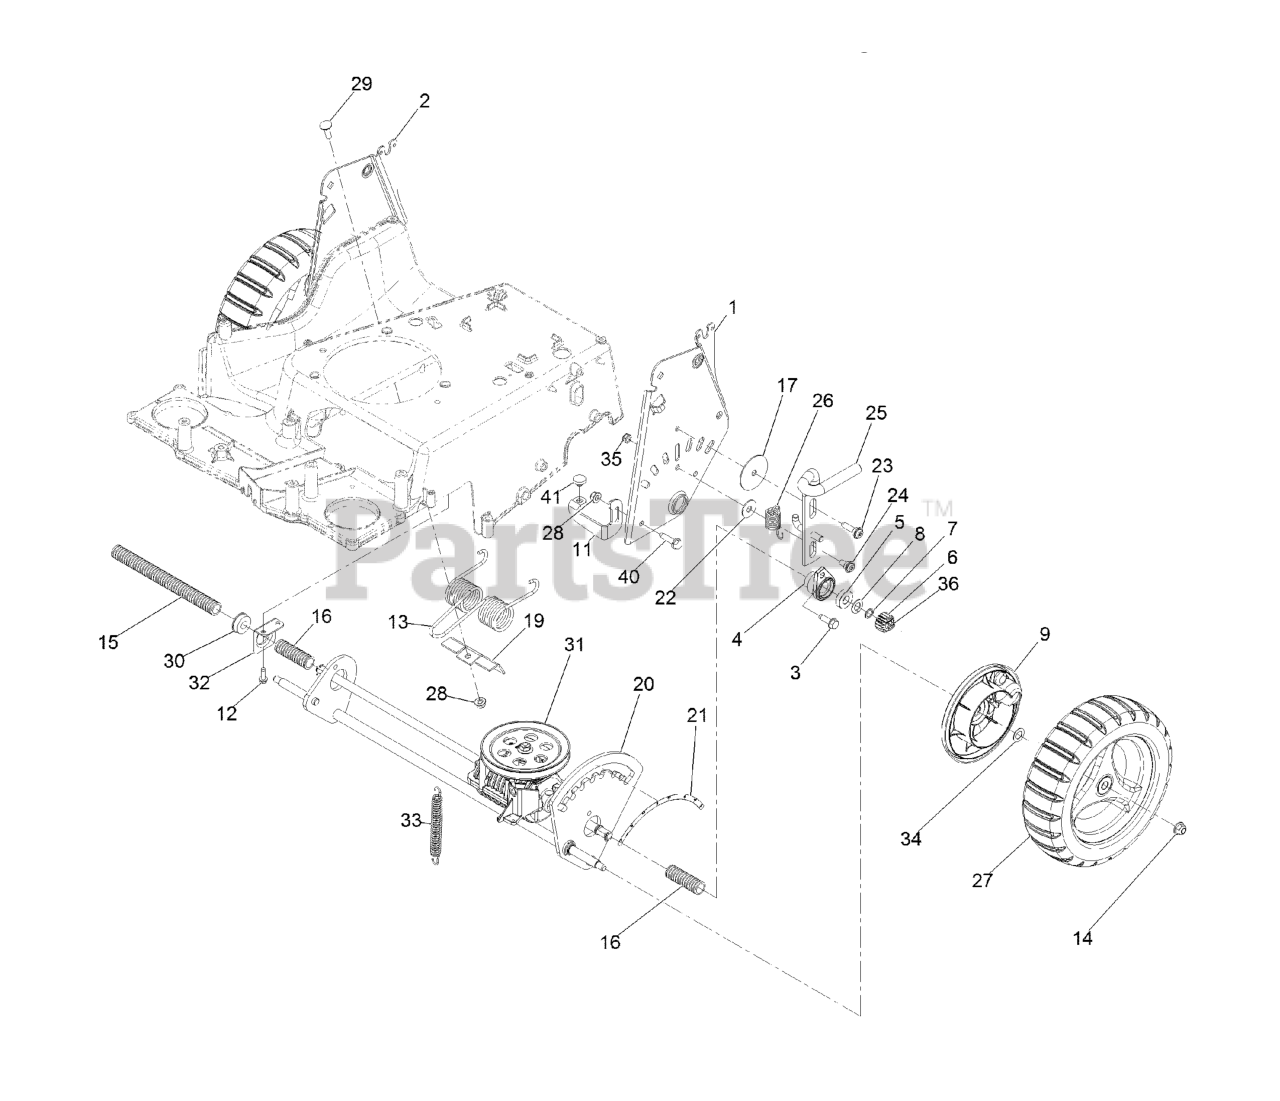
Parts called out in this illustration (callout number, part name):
1	LH HOC PLATE ASM
2	RH HOC PLATE ASM
3	SCREW-THD ROLL, HWH
4	RETAINER-BEARING
5	BEARING-BALL
6	GEAR-PINION, 15T
7	RING-RETAINING
8	WASHER-THRUST
9	COVER,GEAR
11	BRACKET-STOP, ADJUSTABLE
12	SCREW-HWHTF
13	SPRING-TORSION
14	NUT-HF, NI
15	CONDUIT-CONVOLUTED
16	CONDUIT-CONVOLUTED
17	WASHER-PLAIN
19	BRACKET
20	AXLE-REAR
21	DECAL-HOC, REAR
23	SCREW-SHOULDER, BHTF
24	BOLT-SHOULDER
25	LOCK-HEIGHT, ADJ
26	SPRING-EXTENSION
27	WHEEL ASM, 10.5 W/GEAR
28	NUT-HF, NI
29	BOLT-CARR
30	BEARING-BALL
31	TRANSMISSION KIT
32	MOUNT-BEARING
33	SPRING-EXTENSION
34	WASHER-PLAIN
35	NUT-LOCK, NI
36	PIN-SNAP
40	SCREW-HWHTF
